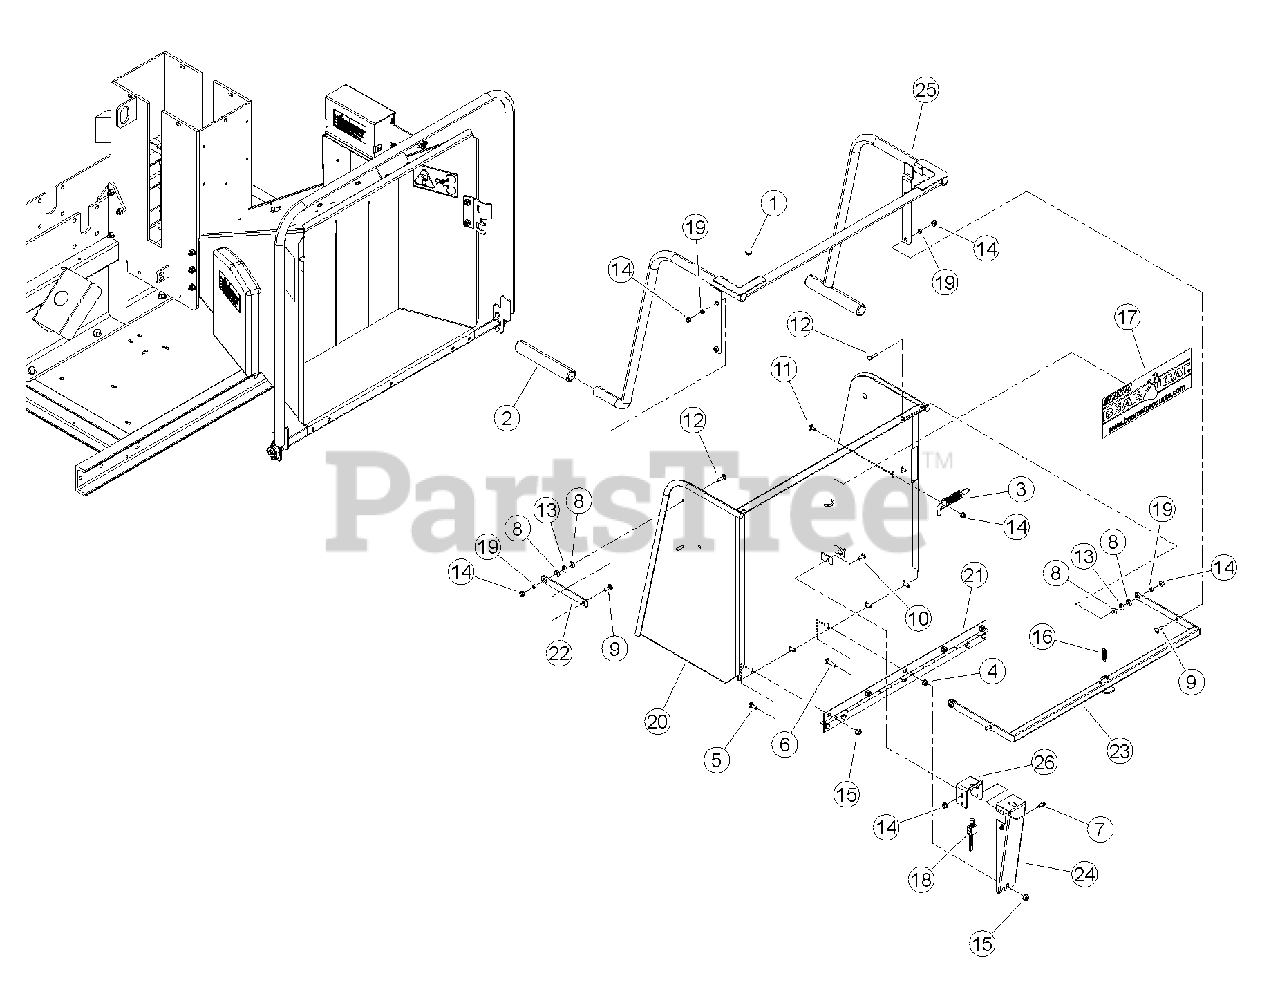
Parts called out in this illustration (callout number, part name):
1	BUMPER, RUBBER
2	GRIP, 1.219 X 10.00
3	LATCH, RH HINGE
4	NUT, 3/8" SERRATED FLANGE NC ZP
5	BOLT, 3/8 X 1" GR5 CRG NC ZP
6	BOLT, 3/8 X 1-1/2" GR5 CRG NC ZP
7	SCREW, 11/32 X 7/8 HWH AB THREAD ZP
8	WASHER, 5/16" FLAT ZP
9	BOLT, 5/16 X 1" GR5 CRG ZP
10	BOLT, 5/16 X 7/8" GR5 CRG NC ZP
11	BOLT, 5/16 X 3/4 GR5 CRG NC ZP
12	BOLT, 5/16 X 1-1/4" GR5 CRG ZP
13	WASHER, 5/16" ID 7/8" OD NYLON FLAT
14	NUT, 5/16-18 NYLOCK-FLANGE
15	NUT, 3/8-16 NYLOCK FLANGE
16	SPRING, 1/2 X 2.00 LG,ZP
17	DECAL, BEARCAT WEB
18	SWITCH, MOMENTARY IP67 NORMALLY ON
19	SPACER, IDLER PIVOT
20	WELDMENT, EXTENSION TRAY
21	HINGE, EXTENSION TRAY
22	LINK, PARALLEL
23	WELDMENT, KNEEBAR PIVOT
24	SHIELD, KNEEBAR SWITCH
25	WELDMENT, KNEEBAR
26	BRACKET, SWITCH
